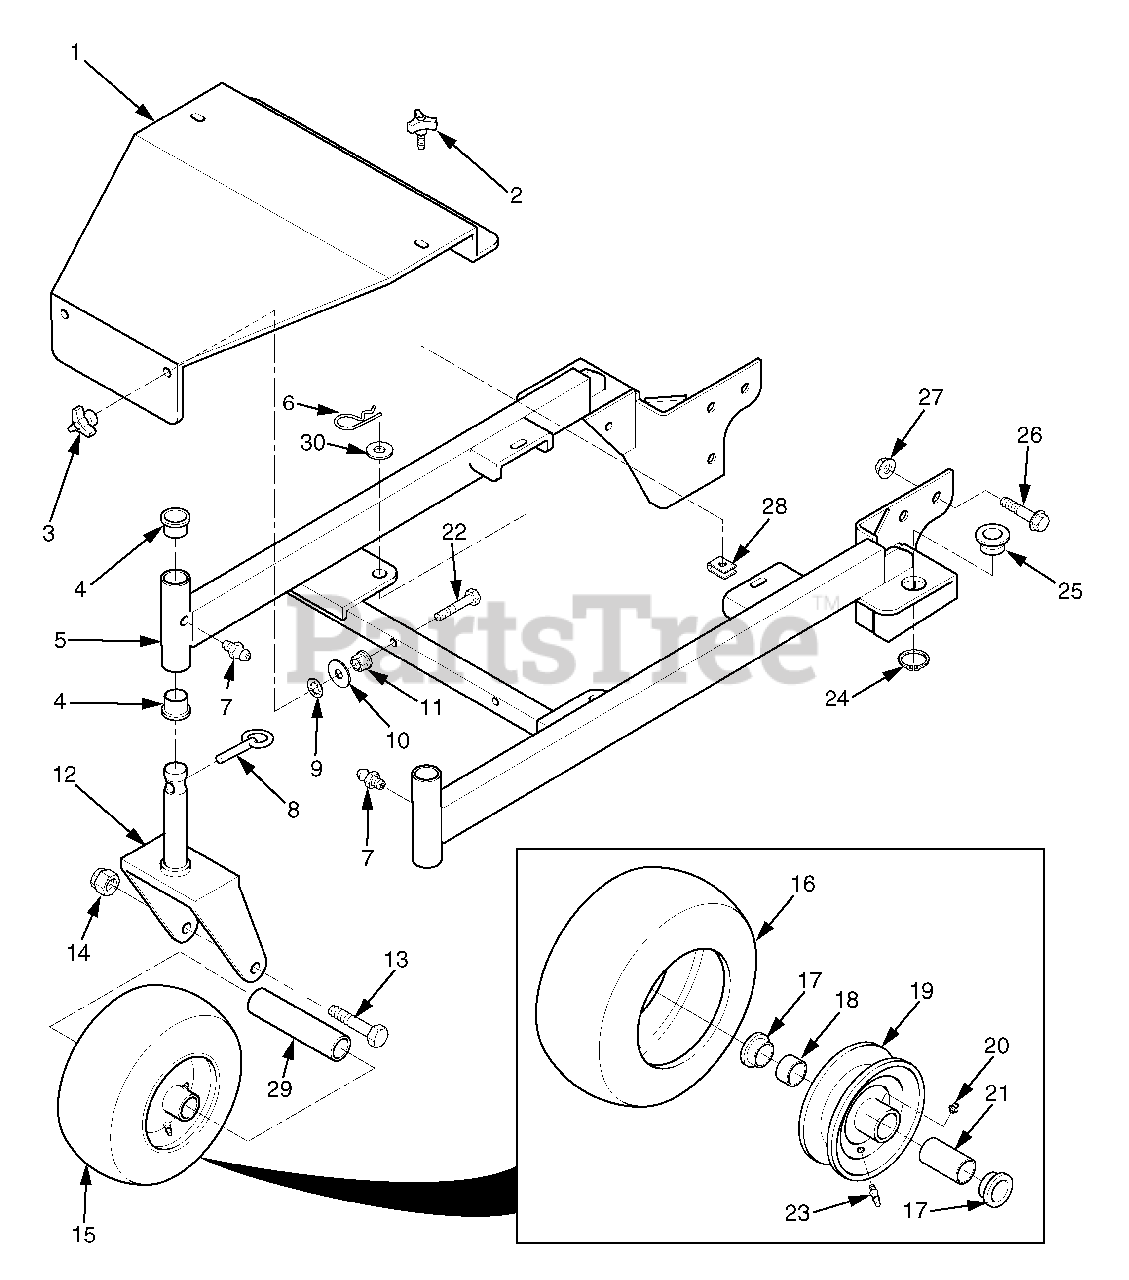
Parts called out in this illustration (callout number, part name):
1	Belt Cover With Decal
2	Knob With Stud
3	Knob, Deck Cover Mounting
4	Bushing, Caster
5	Frame Weldment, Deck Mounting - 36"
6	Hair Pin Cotter, .177" x 3-1/4"
7	Grease Fitting Str. 1/4-28 Self Tap
8	Quick Pin, .438" Dia.
9	Nut, Push-On - 3/8" Dia.
10	Flatwasher, 3/8" (.391 x .938 x .105)
11	Nut, 3/8-16 Serrated Flange Hex Head
12	Yoke, Caster Wheel
13	Capscrew, Hex Head 1/2-13 x 6-1/2"
14	Locknut, 1/2-13 Elastic Stop
15	Wheel Assembly, Caster
16	Tire, 11 x 4.00-5
17	Retainer
18	Roller Bearing
19	Rim, 5.0" x 2.75"
20	Grease Fitting Str. 1/4-28
21	Roller Bearing .625 x 3.25"
22	Capscrew, Hex Head 3/8-16 x 2-1/4"
23	Tire Valve
24	Retaining Ring 1.50 Ext.
25	Bushing, Deck Adjustment Pin
26	Capscrew, 1/2-13 x 1" Serrated Flange Hex Head
27	Nut, 1/2-13 Spiralock
28	U-Nut, 3/8-16
29	Sleeve, Caster Wheel
30	Flatwasher, 5/8" - (.688 x 1.75 x .134)
